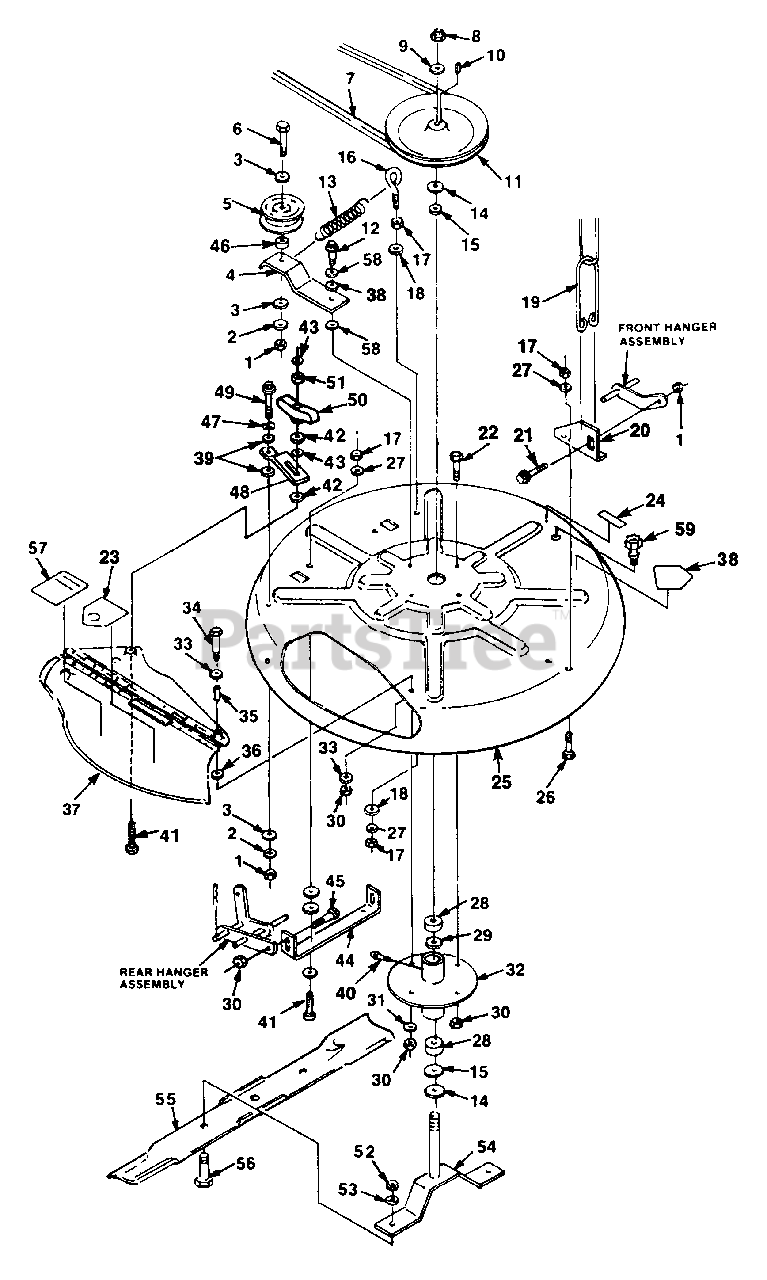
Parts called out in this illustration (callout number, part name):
1	NUT-Hex centerlock 3/8-16
2	WASHER- Lock 3/8
3	WASHER- Flat 3/8
4	ARM- Pivot Idler
5	PULLEY- Idler
6	SCREW- Hex 3/8-16 x 2 1/2
7	BELT- Mower
8	NUT- Hex locking 3/4
9	WASHER- Flat 3/4
10	KEY- 3/16 x 1.00
11	PULLEY- Spindle
12	SCREW- Cap hex hd 5/16-18 x 1.250
13	SPRING- Extension
14	SPACER-.100 Thick
15	WASHER-.036 Thick
16	BOLT- Eye
17	NUT- Centerlock 1/4-20
18	WASHER- Flat 1/4
19	LINK- Lower front lift
20	BRACKET- Front lift
21	BOLT- Shoulder 3/8-16 x 2.125
22	SCREW- Cap hex hd 5/16-18 x .750
23	DECAL- CPSC Warning
24	DECAL- No step
25	DECK- Cutter 30"
26	SCREW- Cap hex hd 1/4-20 x.625
27	WASHER- Lock 1/4
28	BEARING- Cutter shaft
29	SPACER- Bearing
30	NUT- Hex centerlock 5/16-18
31	WASHER- Lock 5/16
32	HOUSING- Spindle
33	WASHER- 5/16 SAE
34	SCREW- Hex 5/16-18 x 5/8
36	WASHER- Flat 3/8
37	PLATE COVER ASSEMBLY
38	SPACER- Idler Arm
39	WASHER- Flat
40	FITTING- Grease
41	SCREW- Cap hex hd 1/4-20 x.750
42	WASHER- Plain 1/4
44	BRACKET- Rear lift
45	BOLT- Shoulder 5/16 x 18
47	WASHER- Spring
48	ARM- Pivot
49	BOLT- Hex hd cap 1/4-20 x .625
50	KNOB- Handle
51	NUT- Hex 1/4-20 hvy
52	NUT- Hex centerlock 1/2-13
53	WASHER- Lock 1/2
54	SPINDLE & ADAPTER
55	BLADE
56	SCREW- Cap hex hd 1/2-13 x 1.25
57	DECAL- Danger
58	WASHER- Idler arm
59	WASHOUT PLUG
